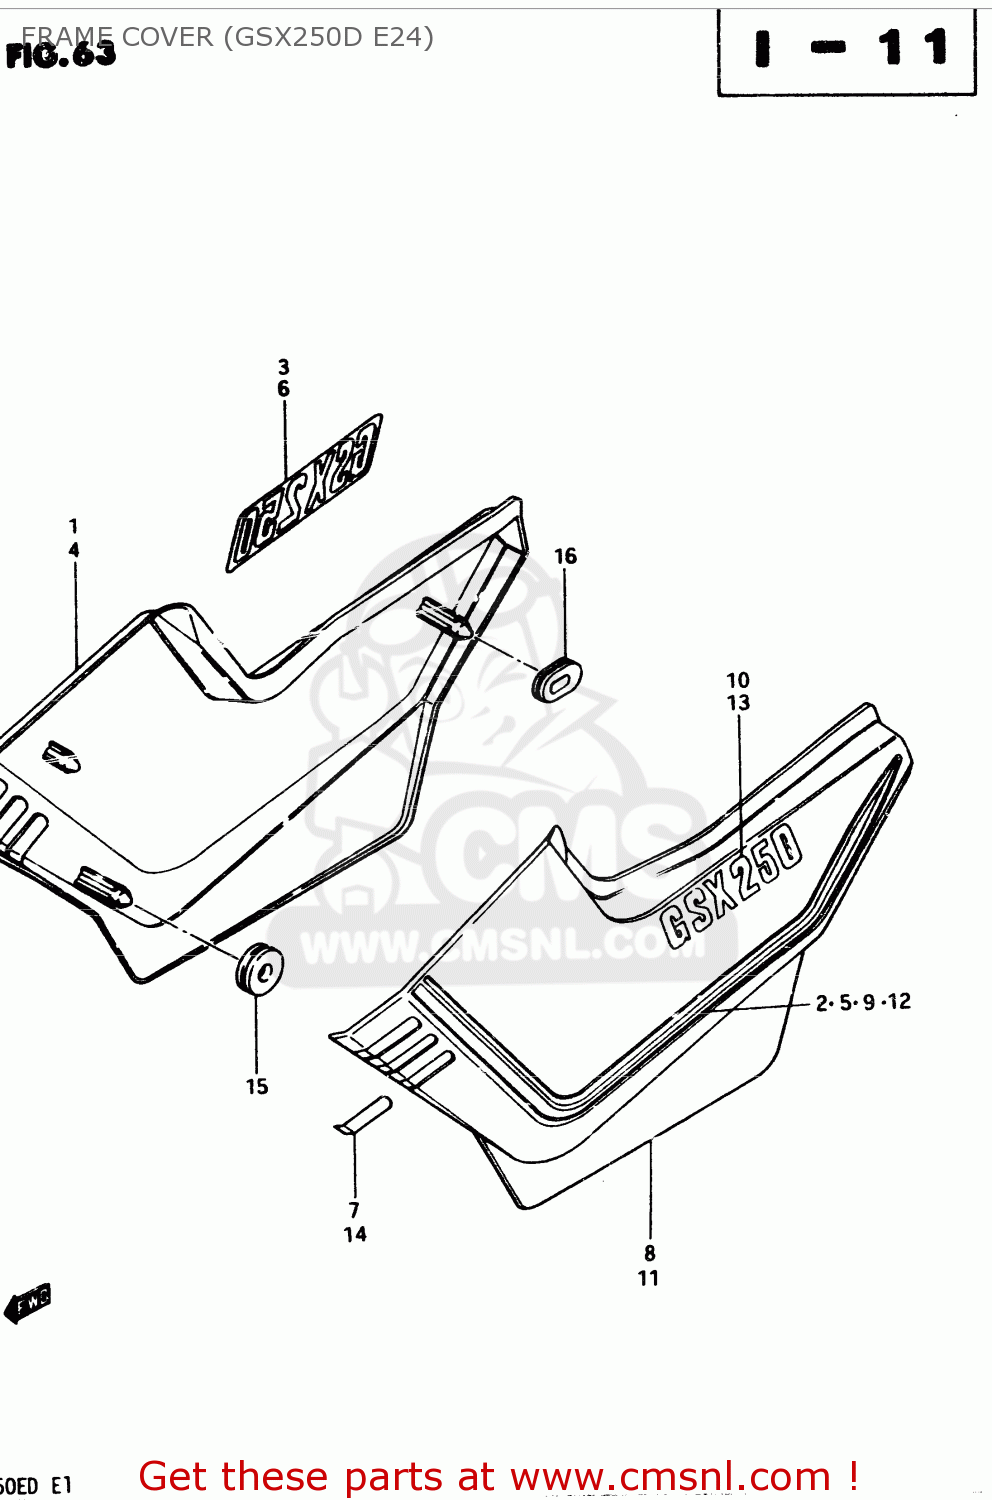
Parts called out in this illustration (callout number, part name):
1	COVER, FRAME RH (RED)
2	TAPE SET, FRAME COVER RH
3	EMBLEM, LH (SILVER)
4	COVER, FRAME RH (SILVER)
5	TAPE SET, FRAME COVER RH
6	EMBLEM, LH (BLACK)
7	LABEL,FRAME COVER DENT
8	COVER,FRAME,L
9	TAPE SET, FRAME COVER LH
10	EMBLEM, LH (SILVER)
11	COVER, FRAME LH (SILVER)
12	TAPE SET, FRAME COVER LH
13	EMBLEM, LH (BLACK)
14	LABEL,FRAME COVER
15	CUSHION
16	CUSHION
